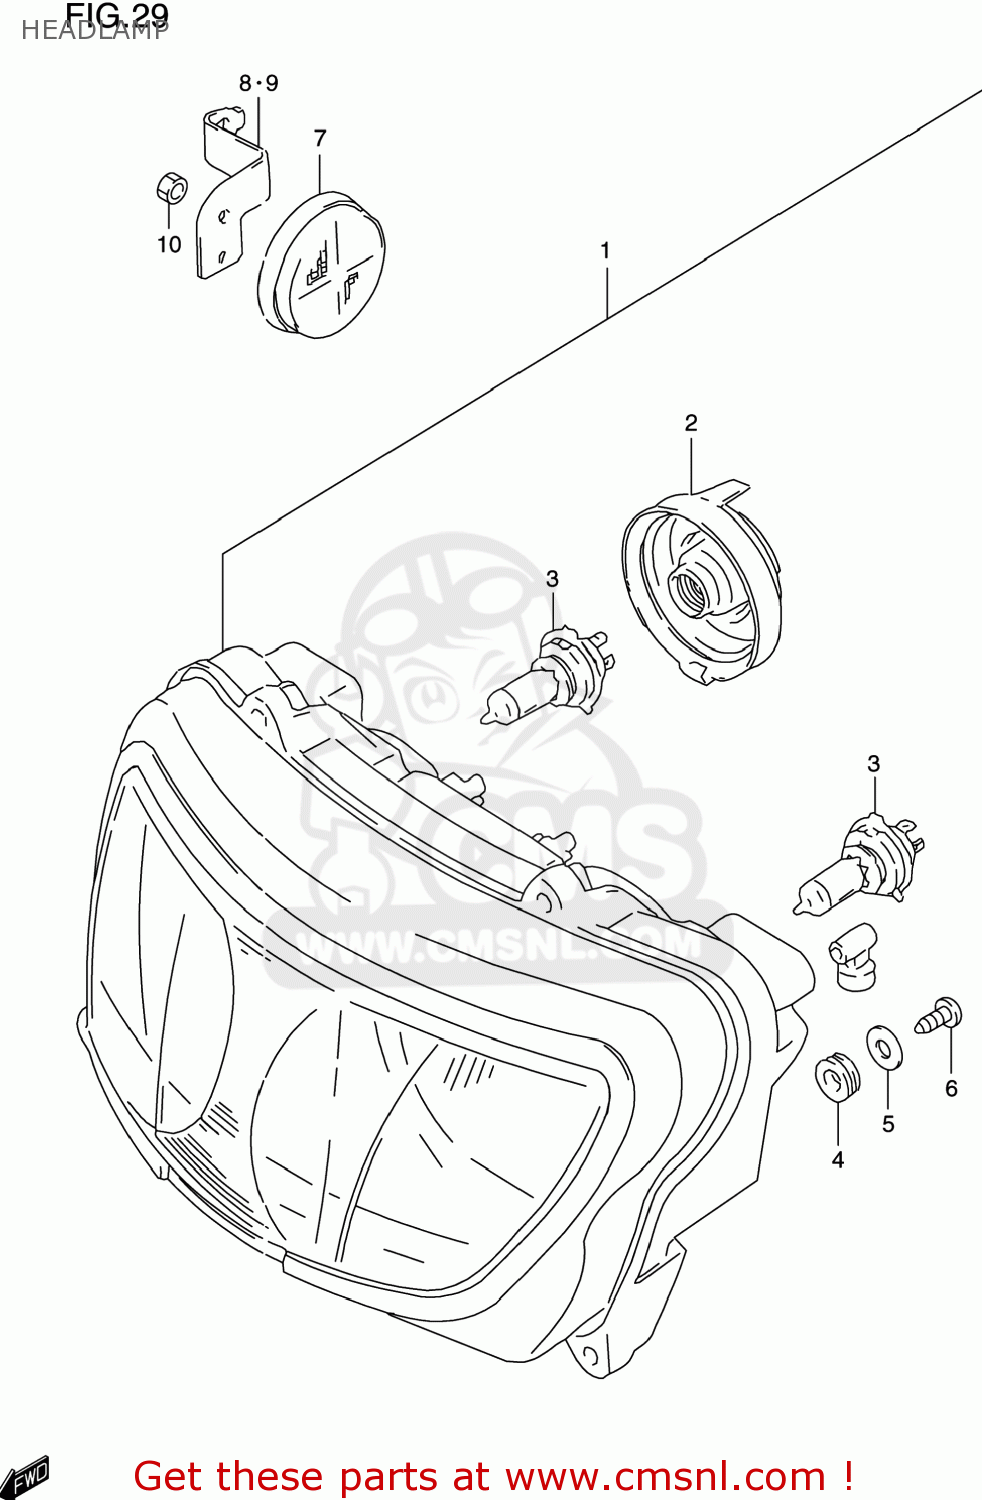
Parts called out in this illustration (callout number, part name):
1	HEADLAMP ASSY
2	COVER,SOCKET
3	BULB(12V55/50W)
4	CUSHION,HEADLAMP
5	WASHER(5.5X18X1)
6	SCREW,SIDE HOL
7	REFLECTOR,REFLEX FR
8	BRACKET,FR SIDE RR,R
9	BRACKET,FR SIDE RR,L
10	NUT
